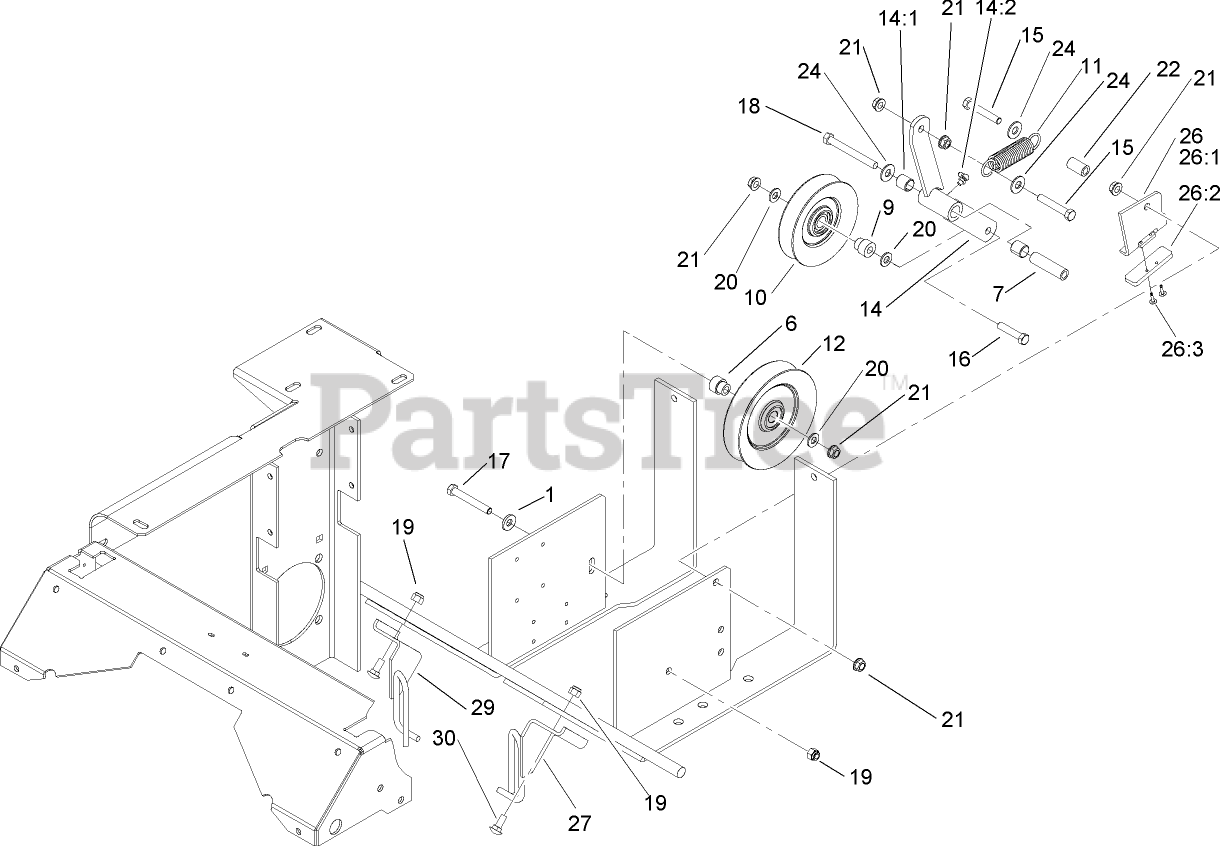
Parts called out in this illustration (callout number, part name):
1	WASHER-BELLEVILLE
6	Bushing-Idler
7	BUSHING-PIVOT, IDLER
9	BUSHING-IDLER
10	Idler
11	SPRING-EXTENSION
12	PULLEY-IDLER
14	Arm ASM
14:1	SLEEVE-BEARING
14:2	FITTING-GREASE, 90 DEG
15	SCREW-HH
16	SCREW-HH
17	SCREW-HH
18	SCREW-HH
19	NUT-LOCK, NI
20	WASHER-FLAT
21	NUT-HHF, WHIZ
22	SPACER
24	WASHER-FLAT
26	Travel Limiter ASM
26:1	Plate-Limiter, Pulley
26:2	PAD-BUMPER
26:3	RIVET
27	GUIDE-BELT, LH
29	GUIDE-BELT, RH
30	BOLT-CARR
